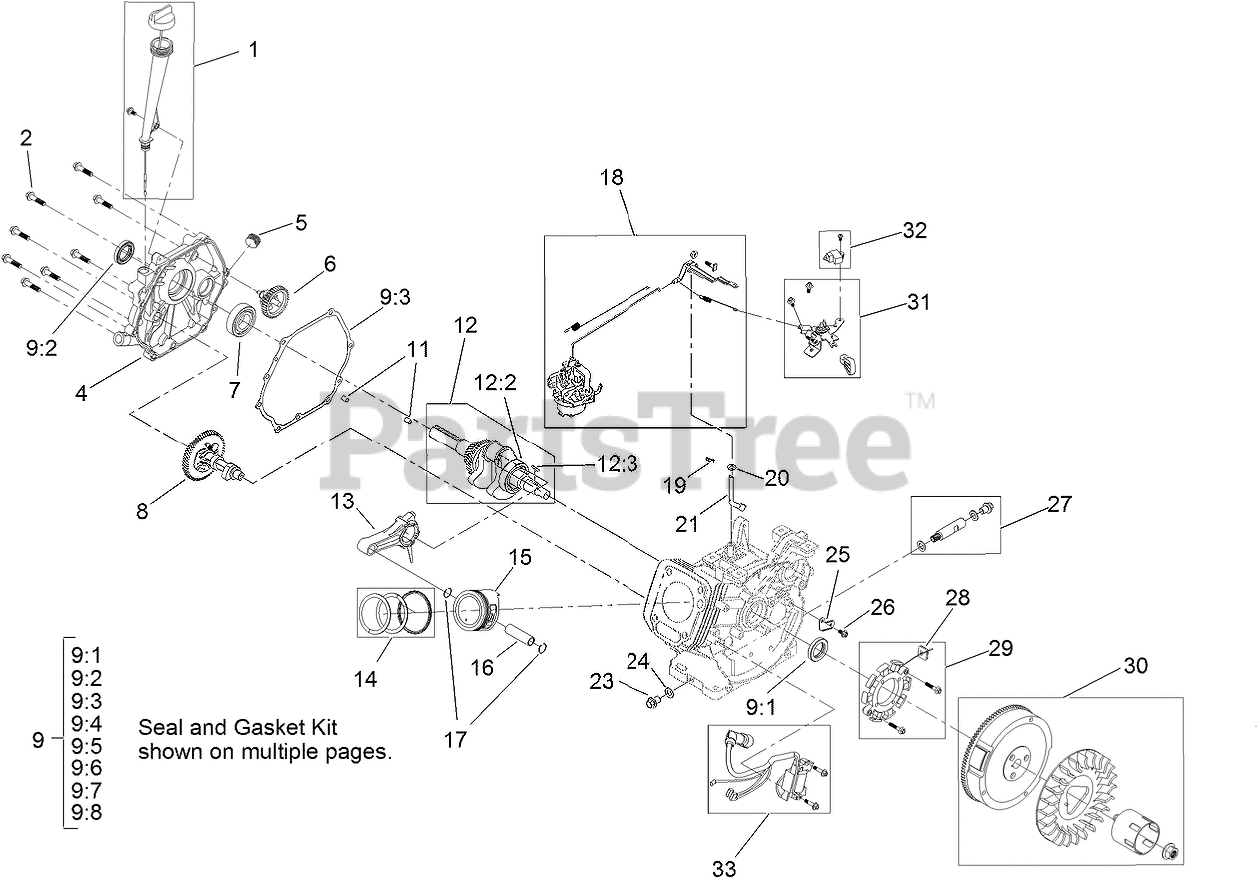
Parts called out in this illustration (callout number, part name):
1	OIL FILL KIT
2	SCREW-HHF
4	COVER-CRANKCASE
5	PLUG-DRAIN
6	GOVERNOR GEAR ASM
7	BEARING-MAIN
8	CAMSHAFT ASM
9	SEAL AND GASKET KIT
9:1	SEAL-OIL
9:2	SEAL-OIL
9:3	GASKET-COVER, CRANKCASE
9:4	GASKET-HEAD, CYLINDER
9:5	GASKET-COVER, VALVE
9:6	GASKET-EXHAUST
9:7	GASKET-CARBURETOR
9:8	GASKET-CARBURETOR
11	PIN-DOWEL
12	CRANKSHAFT ASM
12:2	BEARING-MAIN
12:3	KEY-WOODRUFF
13	CONNECTING ROD ASM
14	SET-RING, PISTON
15	PISTON
16	PIN-PISTON
17	CLIP-PIN, PISTON
18	COMPLETE GOVERNOR KIT
19	PIN-HAIR
20	WASHER-PLAIN
21	SHAFT-GOVERNOR
23	SCREW-HHF
24	WASHER-PLAIN
26	SCREW-HHF
27	DRAIN PLUG KIT
28	GROMMET-RUBBER
29	STATOR KIT
30	FAN AND FLYWHEEL KIT
31	THROTTLE CONTROL KIT
32	KILL SWITCH KIT
33	IGNITION KIT
